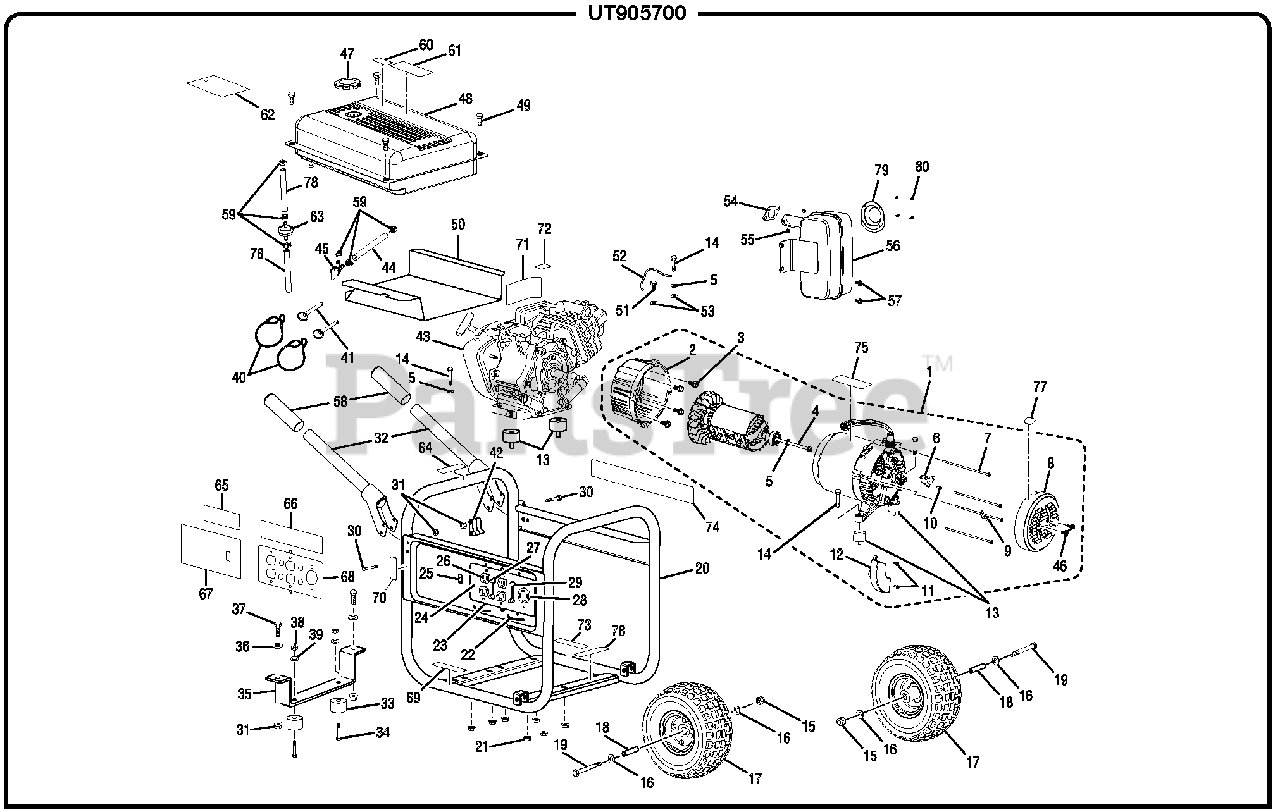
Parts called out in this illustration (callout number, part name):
1	Generator Head Assembly
2	Adapter Housing
3	Bolt, Wiz (3/8-18 x 1-1/4 in.)
4	Bolt (5/16-24 x 6-5/8 in., Hex Hd.)
5	Lock Washer (5/16 in.)
6	Brush Assembly
7	Bolt, Stator 5.7kW
8	Brush Cover
9	Ground Lug
10	Bolt, Mounting Brush Assembly
11	Bolt, Mounting AVR
12	Automatic Voltage Regulator
14	Bolt (5/16-18 x 1 1/2 in., Hex Hd.)
15	Lock Nut (3/8-16)
16	Washer, Flat (3/8 in.)
17	Wheel (10 in.)
18	Wheel Spacer
19	Bolt (3/8-16 x 4-1/4 in.)
20	Frame Assembly
21	Flange Nut (5/16-18)
22	Cord Retainer
23	Screw (6-20 x .38 in.)
24	Wire Panel
25	Switch, Engine Stop
26	Recepticle (120 V, 20 Amp)
27	Circuit Breaker 20 Amp Single Pole
28	Recepticle (240 V, 30 Amp)
29	Circuit Breaker 25 Amp Single Pole
30	Bolt (1/4-20 x 1 in)
31	Lock Nut (5/16-18)
32	Handle Assembly
33	Rubber Foot
34	Bolt (1/4-20 x 1/2 in.)
35	Front Foot Bracket
36	Washer (5/16 in.)
37	Bolt (5/16-18 x 1 in. Hex Hd.)
38	Nut, Nyloc (1/4-20)
39	Washer (1/4 in.)
41	Handle Lock Pin
42	Handle Bracket Spacer
43	Engine (Yamaha OHV)
44	Fuel Line (145 mm)
45	Fuel Shut Off Valve
48	Fuel Tank Assembly
49	Screw (1/4-20 x 1 in.)
50	Heat Shield
51	Bolt (5/16-18 x 3/4 in., Hex. Hd.)
52	Ground Wire Assembly
53	Washer (5/16 in.) External Star
55	Nut (8 mm)
57	Bolt (5/16-24 x 5/8 in.)
58	Handle Grip
59	Fuel Line Clamp
60	E85 Label
61	CPSC Label
62	Caution Hang Tag
63	Fuel Filter
64	Risk of Fire Danger Label
65	Ground Warning Label
66	Powered By Yamaha Label
67	Logo Label
68	Control Panel Label
69	Engine Lubricant Label
70	Lock Pin Label
71	Starting Label
72	Choke Label
73	Hot Surface Label
74	Danger Label
75	Data Label
76	UL Fire Warning Label
77	Ground Label
78	Fuel Line (105 mm)
79	Spark Arrestor
80	Screw (8-32 x 3/8 in.)
